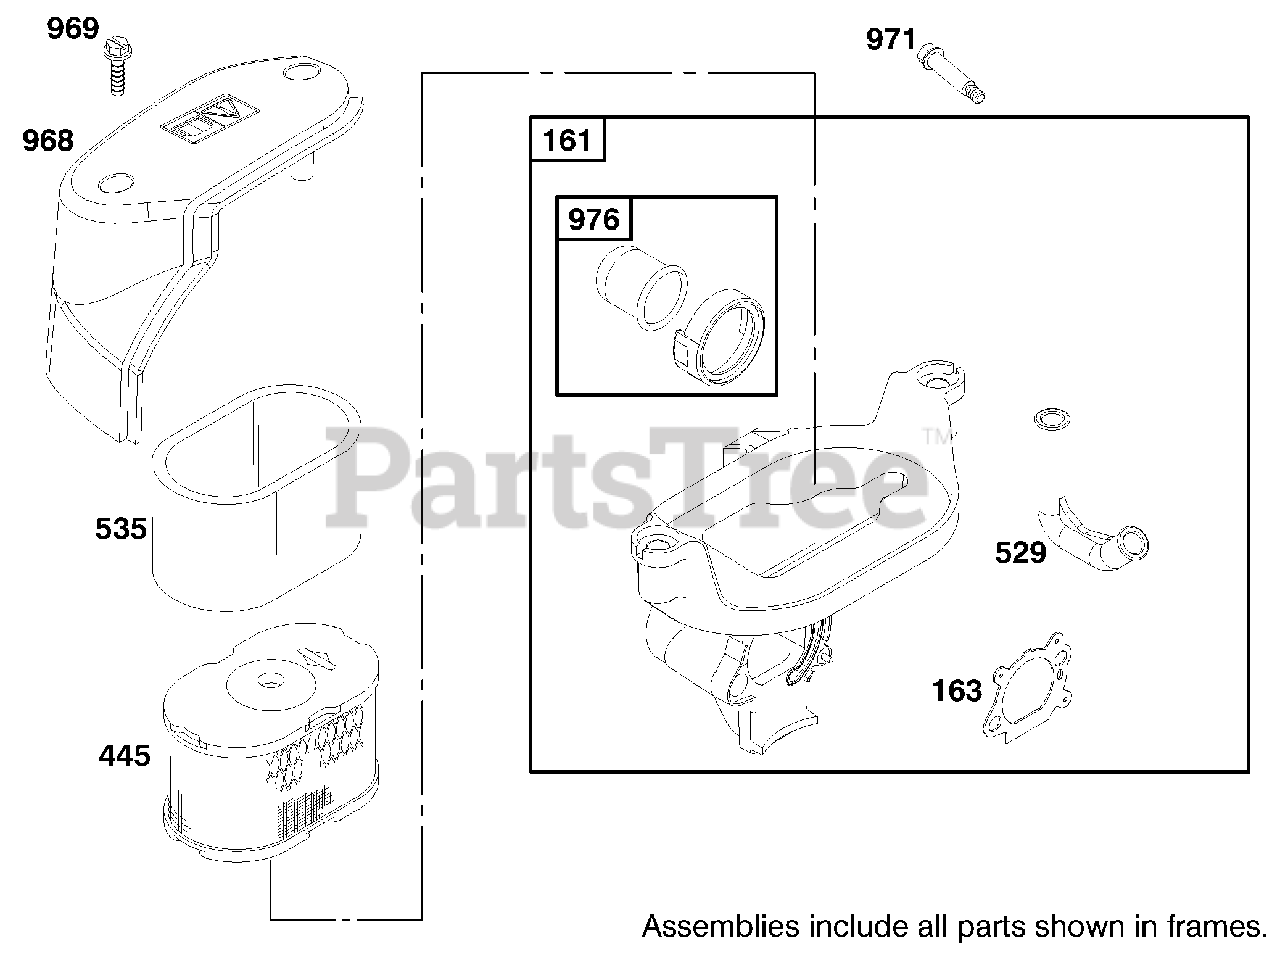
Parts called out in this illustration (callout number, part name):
161	Base-Air Cleaner
163	Gasket-Air Cleaner
445	Filter-Air
529	Grommet-Breather
535	Filter-Air
968	Cover-Air Cleaner
969	Screw-Slotted Hex.
971	Screw-Shoulder
976	Primer-Carburetor
